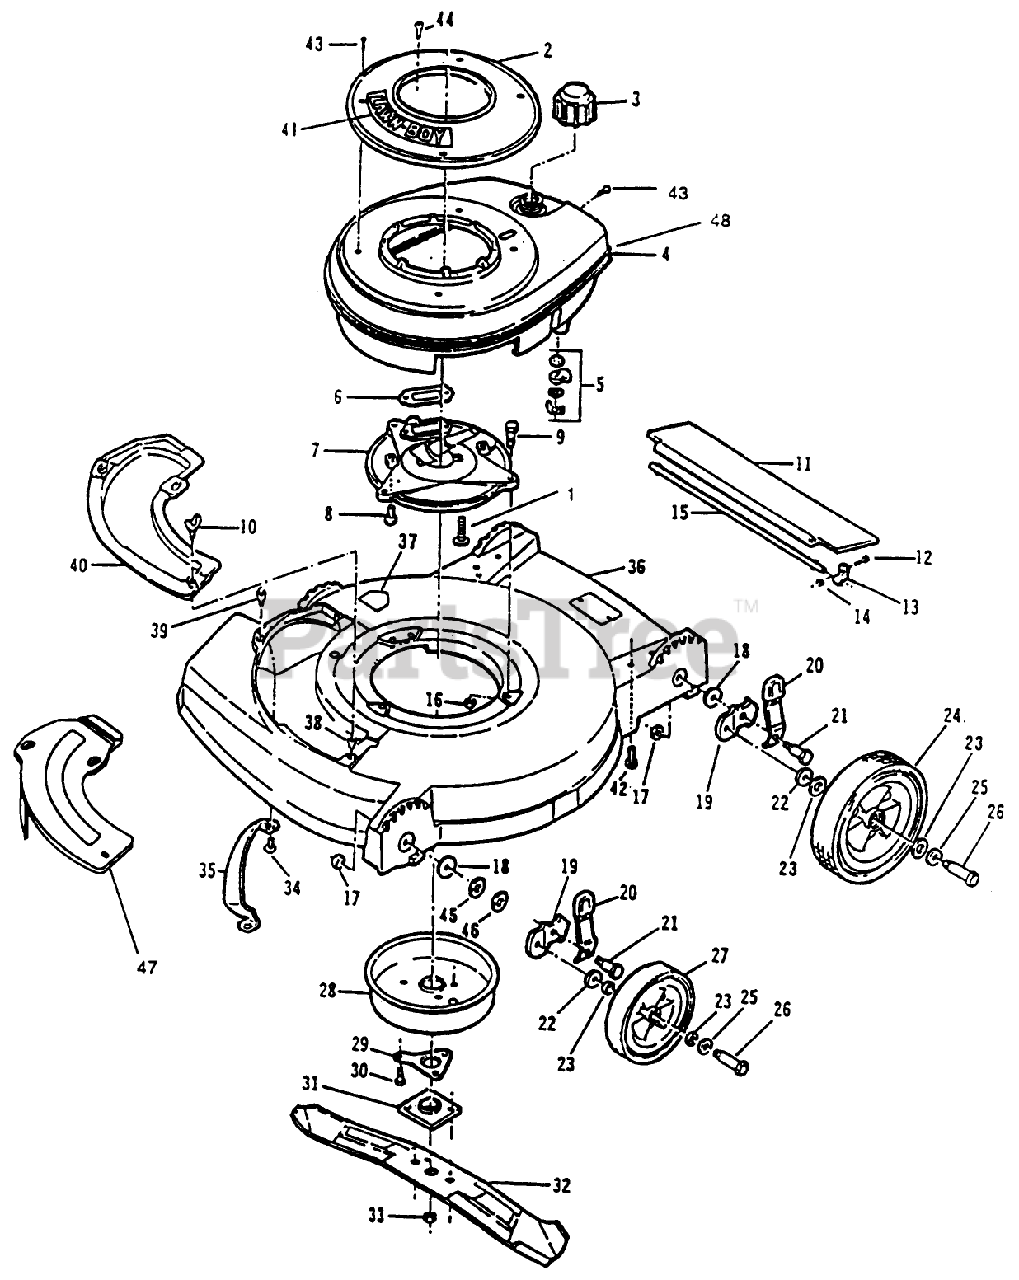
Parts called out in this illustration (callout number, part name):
1	SCREW-SEMS F
2	STARTER BASE&NUT*B
3	FUEL CAP & INSERT
4	SHROUD,TANK&VAL
5	SHUT OFF VALVE KIT
7	PLATE F
8	SCREW V
9	SCREW-HH
10	WING SCREW LAWRE
13	CLAMP ROD KMC
14	LOCKNUT E
15	ROD 21" ADVANCE
16	NUT-LOCK F
17	LOCKNUT
18	WASHER
20	SPRING ARM ASM
21	BOLT
22	WASHER WROUGHT
23	WASHER
25	SPACER
26	BOLT WHEEL
27	WHEEL & TIRE KIT
28	MUFFLER COVER F
29	SUPPORT F
30	SCREW
31	PLATE AND COLLAR ASM
33	NUT-BLADE
35	BAR-TOE
36	HSG AY-SERV-21"*G
42	SCREW
43	SCREW - SELF TAPPING
44	SCREW SEMS SM
45	WASHER
46	WASHER
